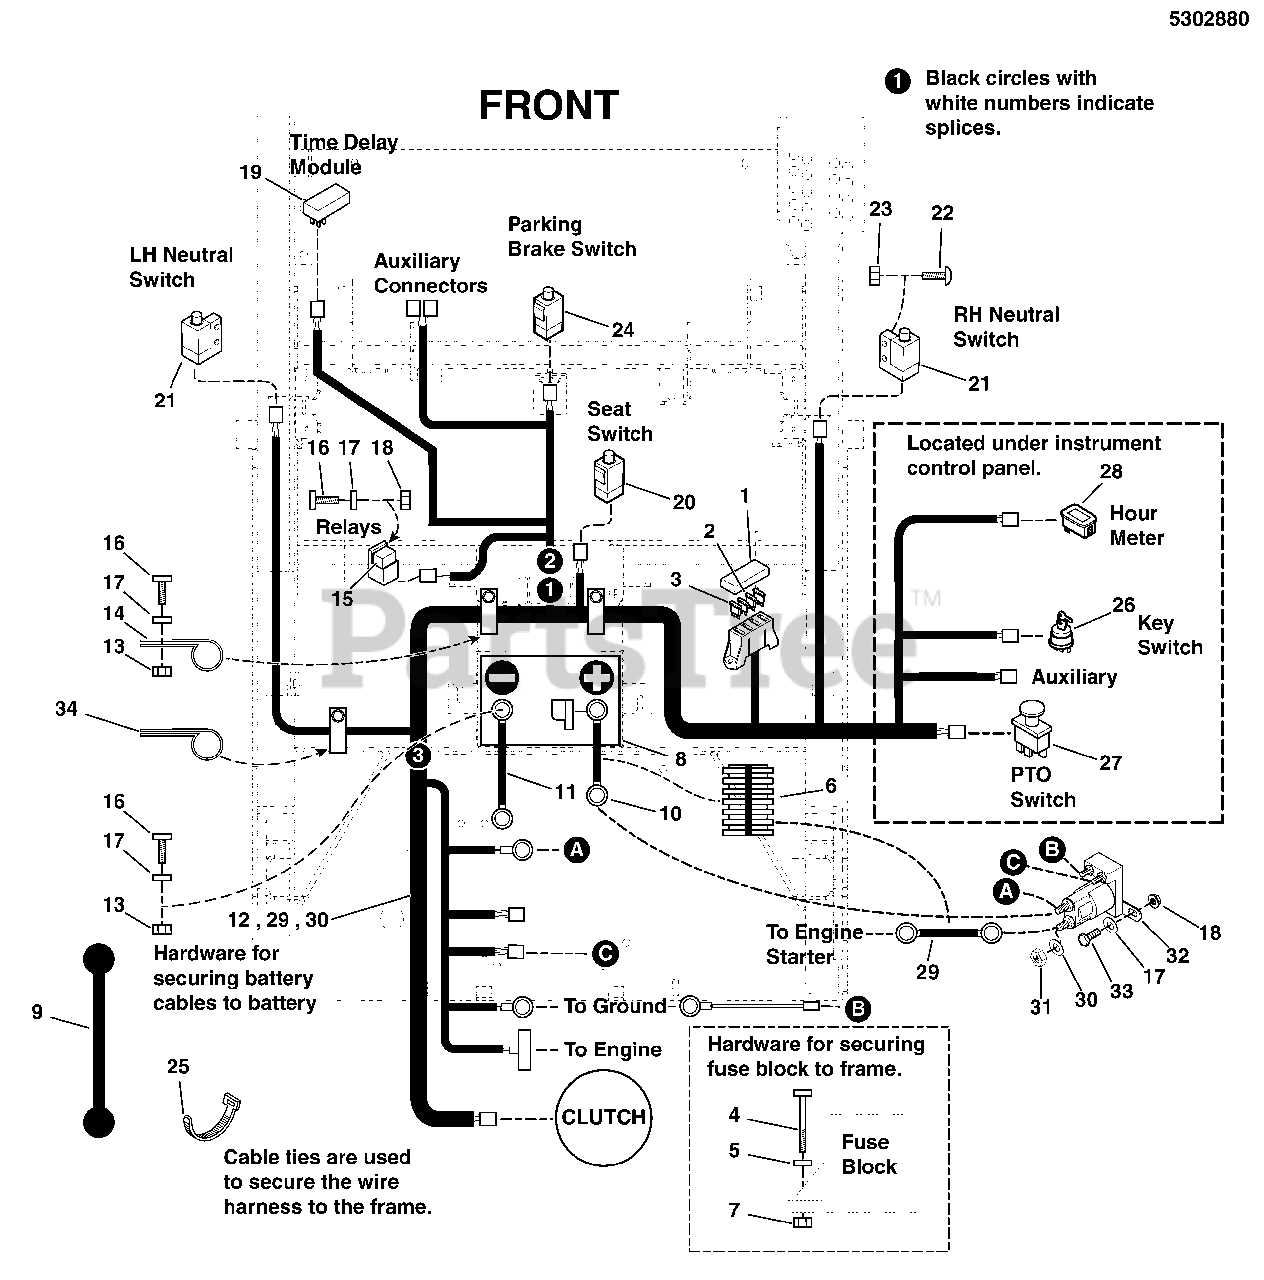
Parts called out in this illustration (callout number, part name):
1	COVER, VINYL FUSEBLOCK
2	FUSE, ATO-15 (15 AMP)(SV)
3	FUSE, ATO-20 (20 AMP)(SV)
4	SCREW, #10-24 X 2 ROUND PHILLIPS
5	WASHER, #10 SAE
6	WIRE LOOM, 3/8 ID X 17 IN
7	NUT, #10-24 HEX NYLON LOCK
8	BATTERY, 11U1L, 350 CCA
9	STRAP-BLACK RUBB
10	BATTERY CABLE, NEG, 14, 5/16-13/32
11	BATTERY CABLE, POS, 15, 1/4-5/16
12	WIRE HARNESS, S200XT M49 VANGUARD
13	NUT, 1/4-20 HEX NYLOCK FLANGE
14	CLAMP, VINYL INSULATED
15	RELAY, 12V, 40A
16	BOLT, 1/4-20 X 3/4 GD5 CZ
17	WASHER, 1/4 SAE
18	NUT, 1/4-20 HEX SERR. FLANGE
19	MODULE, TIME DELAY
20	SWITCH, PLUNGER, NO/NO SNAP-IN
21	SWITCH, PLUNGER, N.O.
22	SCREW, #10-24 X 3/4 ROUND PHILLIPS
23	NUT, #10-24 HEX
24	SWITCH, DP NO/NC SNAP-IN
25	TIE, SELF-LOCKING, 12"
26	SWITCH, IGNITION, 6 POST (SEE INSTRUMENT CONTROL PANEL GROUP)
27	SWITCH, BLADE ENGAGEMENT (SEE INSTRUMENT CONTROL PANEL GROUP)
28	HOUR METER (SEE INSTRUMENT CONTROL PANEL GROUP)
29	BATTERY CABLE, POS, 15, 1/4-5/16
30	WASHER, 5/16 LIGHT LOCK (SV)
31	NUT, 5/16-24 JAM (SV)
32	SOLENOID-4 POLE 12 VOLT DC (TROMBETTA)
33	HHCS, 1/4-20 X 0.625, GR5, ZINC/CLEAR
34	CLAMP, VINYL INSULATED, .625
